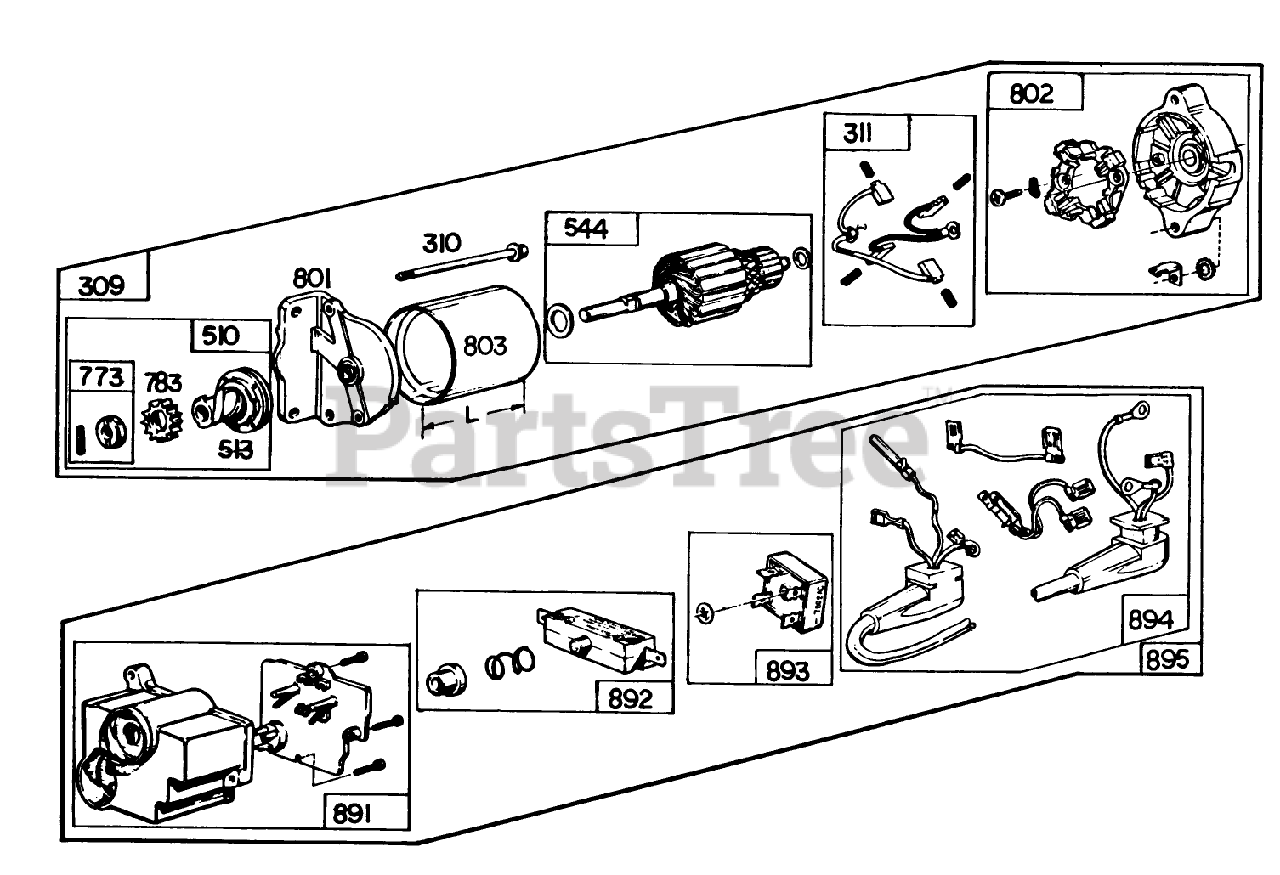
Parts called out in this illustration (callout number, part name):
309	Motor Drive Assembly
310	Thru Bolt Assembly
311	Brush Assembly
510	Drive Assembly
513	Clutch Assembly
544	Armature Assembly
773	Gear-Starter
801	Drive End Cap Assembly
802	Comm. End Cap Assembly
803	Housing Assembly
891	Housing Group
892	Switch Group
893	Rectifier
894	Lead Group
895	Control Group
